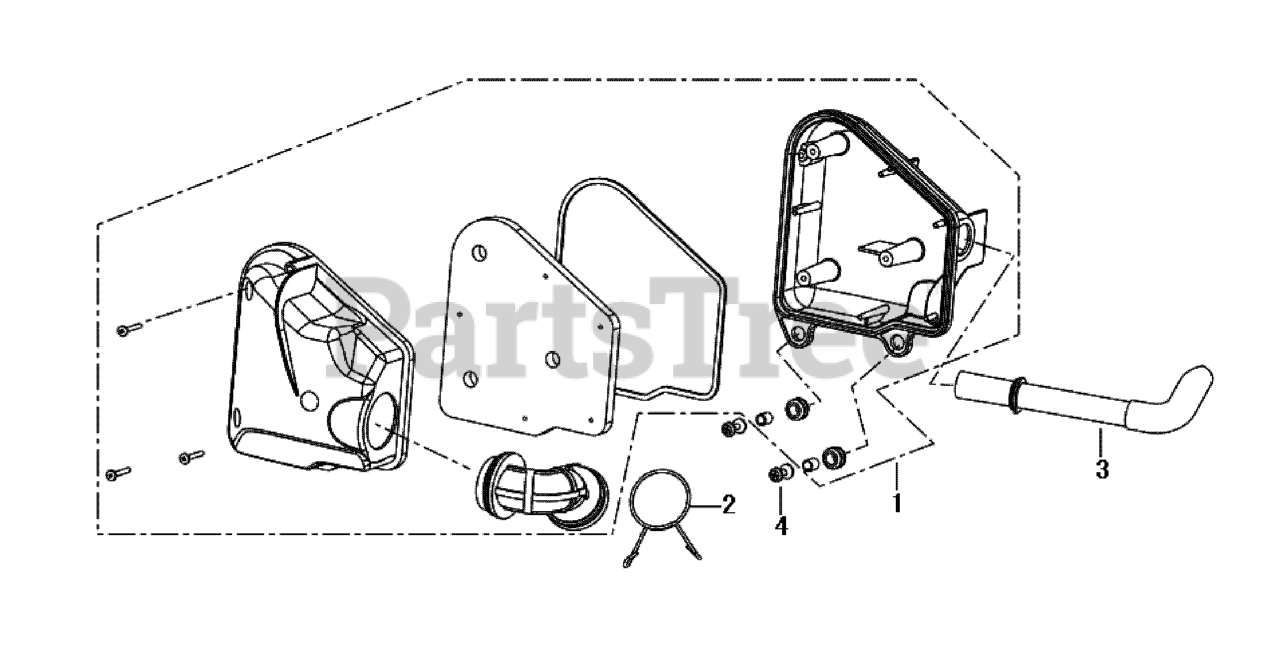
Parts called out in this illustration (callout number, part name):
1	AIR CLEANER ASSY.
2	CLIP, SPRING
4	SCREW-WASHER ASSY.
